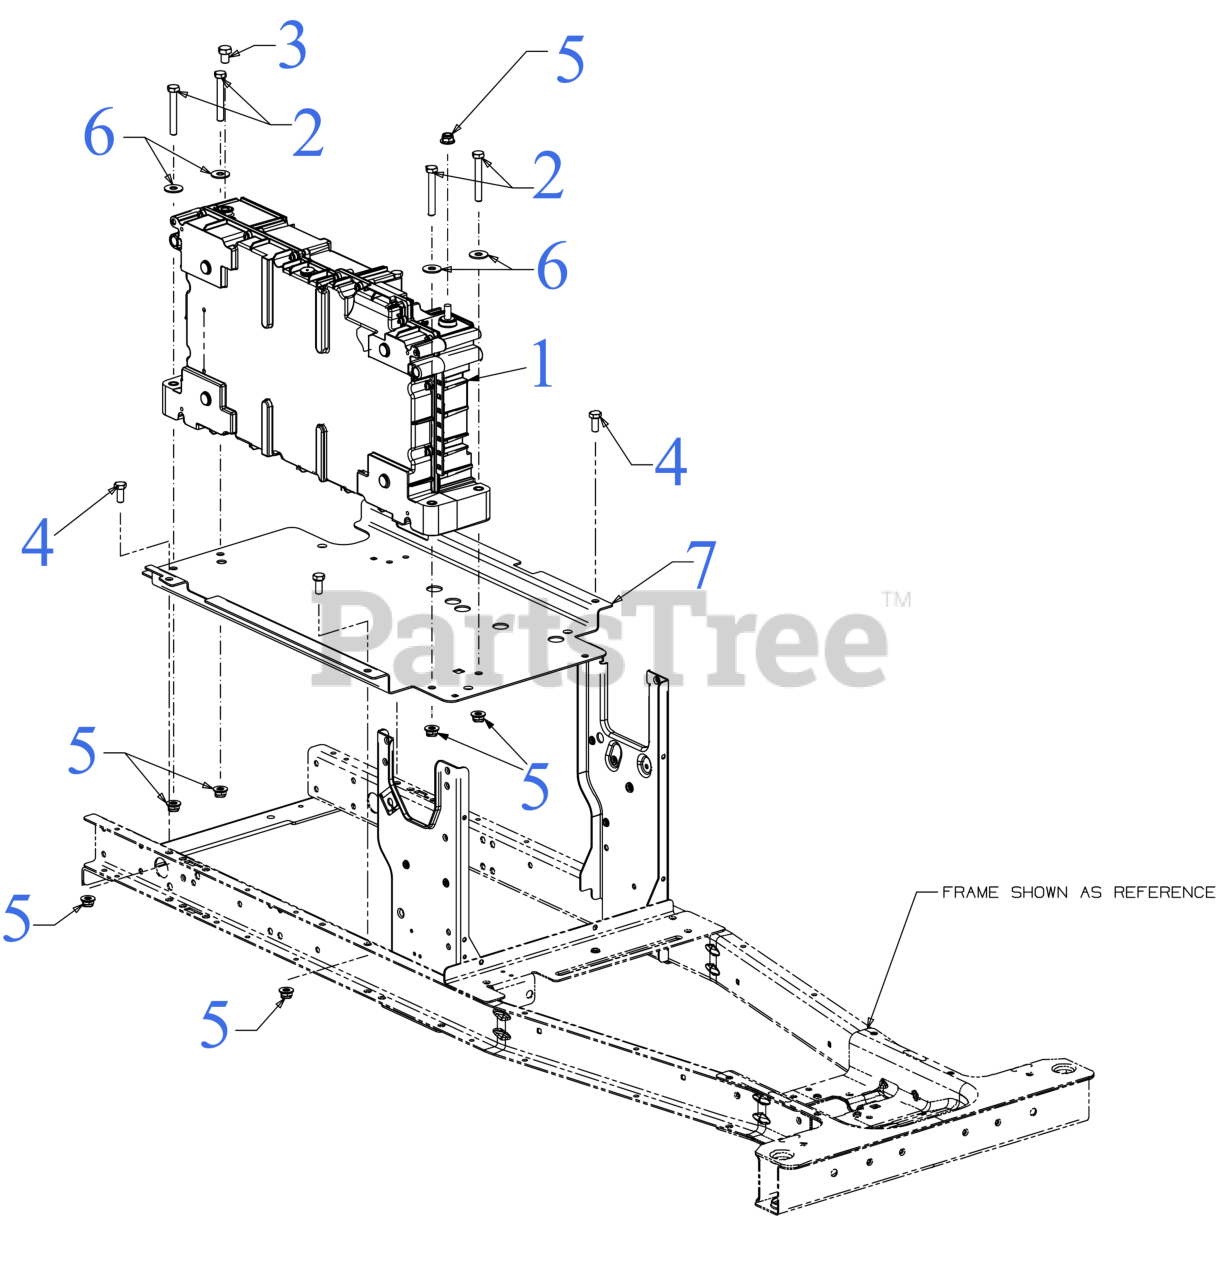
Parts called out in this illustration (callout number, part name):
2	HEX SCREW 5/16-18 x 2.25 GR5
3	SCREW 3/8-24 x .50" GR5 STD
4	SCREW 5/16-18 x .75 GR5
5	FLANGE LOCK NUT 5/16-18
6	FLAT WASHER
7	SWITCH MOUNT BRACKET
